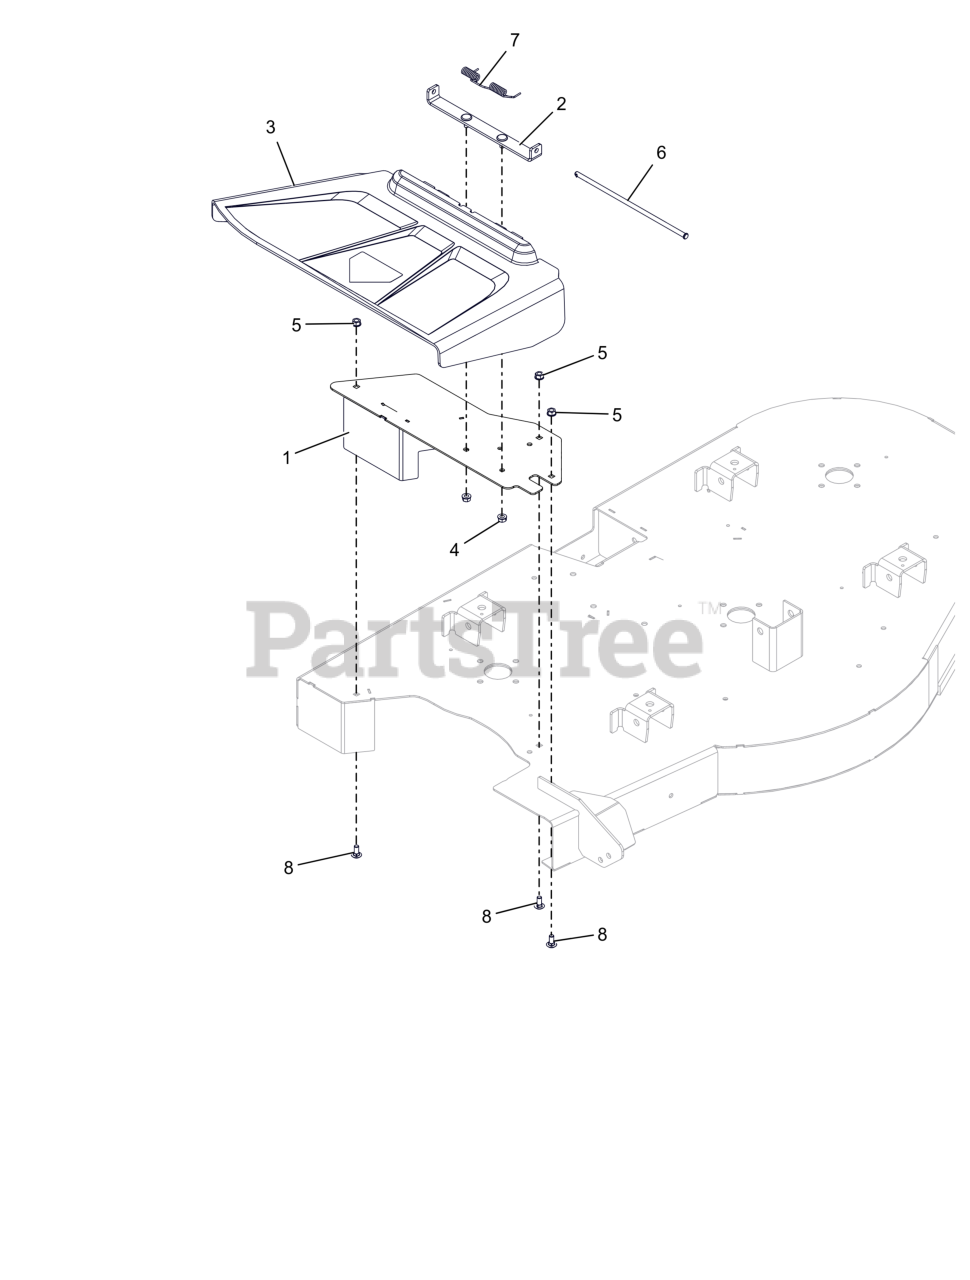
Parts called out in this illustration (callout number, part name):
1	WLDMT, DISCHARGE PLATE (ORANGE)
3	CHUTE, SIDE DISCHARGE
4	NUT-LK-TOP-FLG .312-18 GF ZCC
5	NUT,LK-CTR-FLG .31-18 GF ZCC
6	PIN, SLIC-.312X10.45
7	SPRING-TORSION
8	BLT,RHSN .31-18X.75 G5 ZCC
